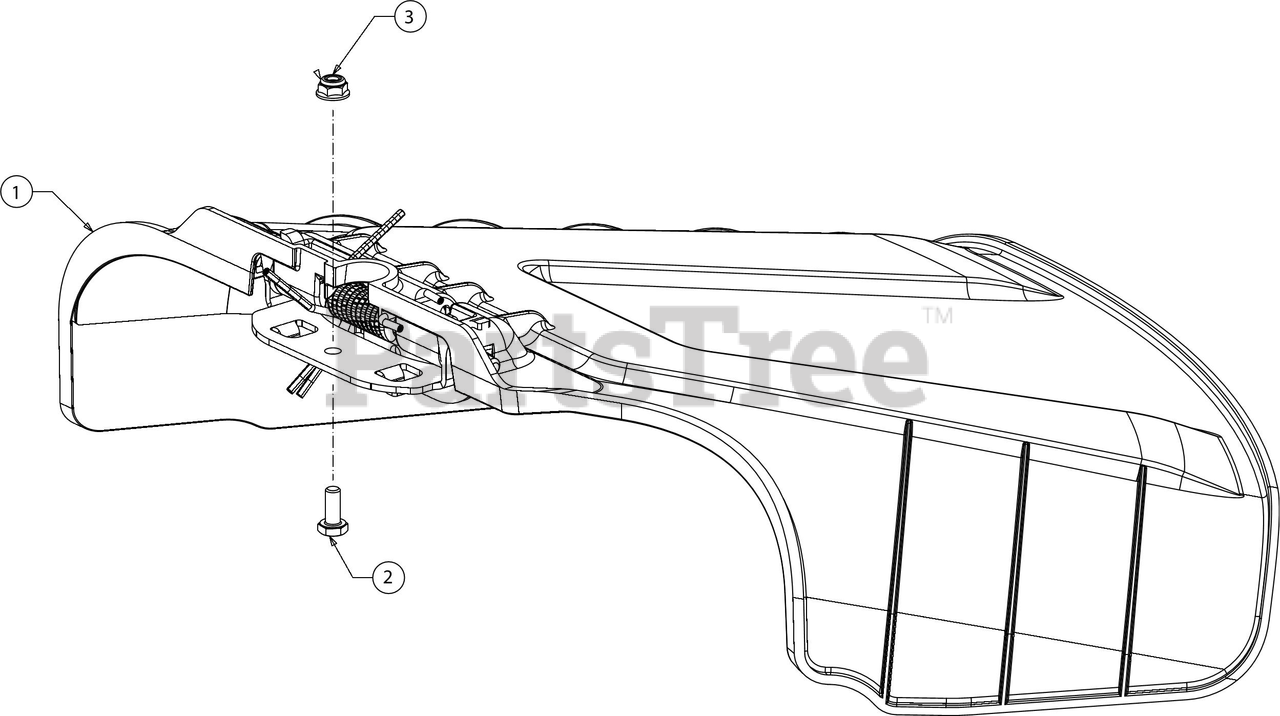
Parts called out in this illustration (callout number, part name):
1	CHUTE ASSEMBLY
2	SCREW 1/4-20 X .620 GR5
3	FLANGE LOCK NUT
